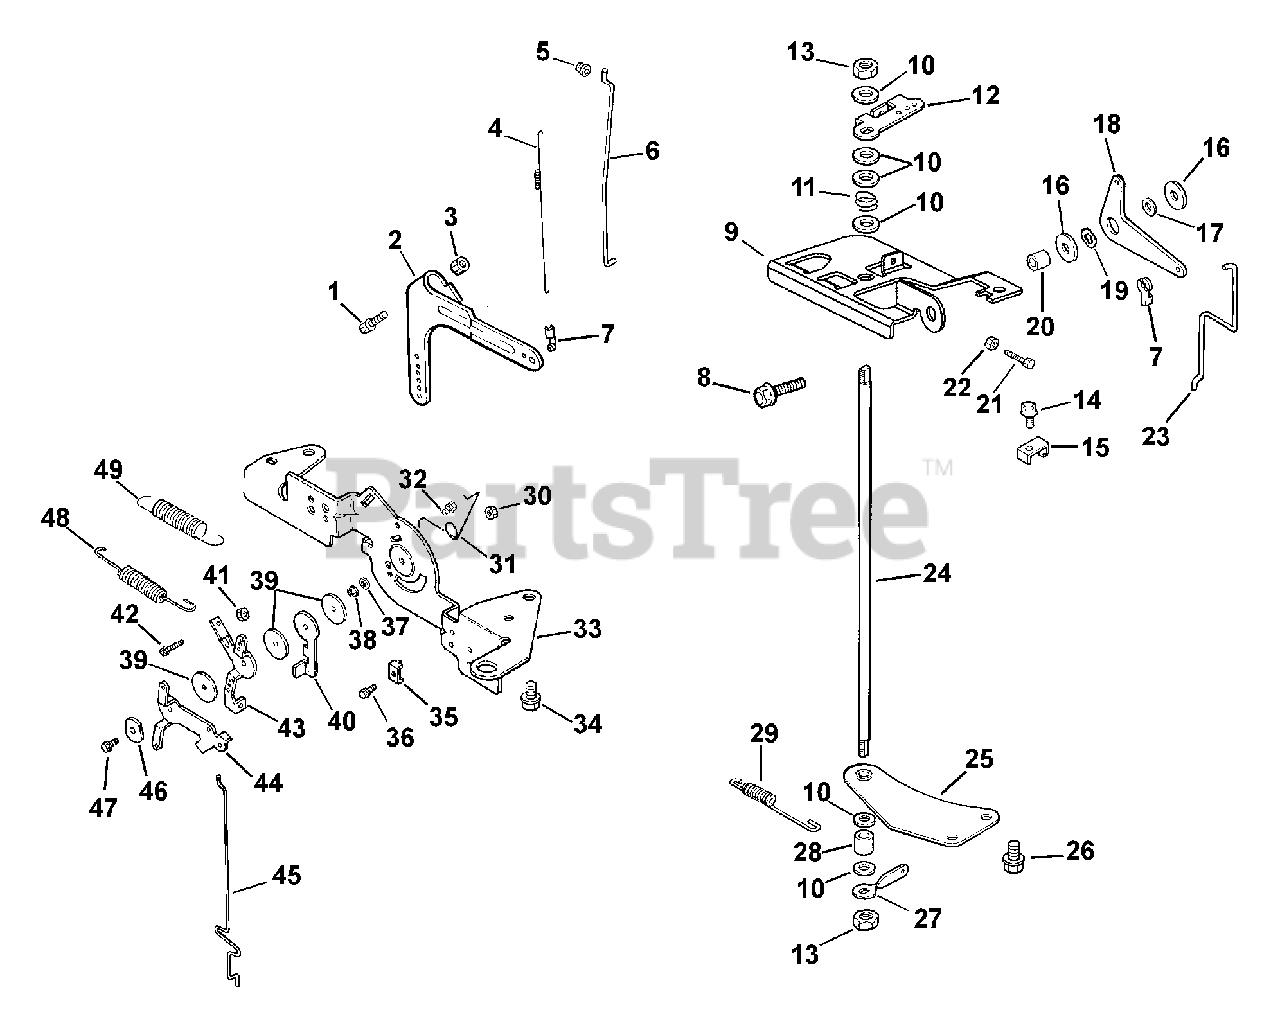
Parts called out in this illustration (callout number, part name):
1	BOLT, RD HD SQ NECK M6X1.0X25
2	LEVER, GOVERNOR-USE 24 090 57-S
3	NUT, FLG M6X1.0
4	SPRING, LINKAGE
5	BUSHING, LINKAGE RETAINING
6	LINKAGE, THROTTLE
7	BUSHING, THROTTLE LINKAGE
8	SCREW, FLG M6X1.0X30
9	BRACKET, SPEED CONTROL
10	WASHER, FLAT 1/4"
11	SPRING, THROTTLE SHAFT
12	LEVER, THROTTLE CONTROL
13	NUT, LOCK M6X1.0
14	SCREW, HEX WASHER HEAD
15	CLAMP, CABLE
16	WASHER, FLAT 1/4"
18	LEVER, CHOKE
19	WASHER, SPRING 3/8"
21	SCREW, CAP M4X.7X30
22	NUT, M4X0.7
23	LINKAGE, CHOKE
24	SHAFT, THROTTLE - DISCONTINUED
25	BRACKET, THROTTLE SHAFT-USE 24 126 162-S
26	SCREW,FLG THD FRM M6X1.0X16-(#25086397S)
27	LEVER, THROTTLE CONTROL
29	SPRING, GOVERNOR (ORANGE)
